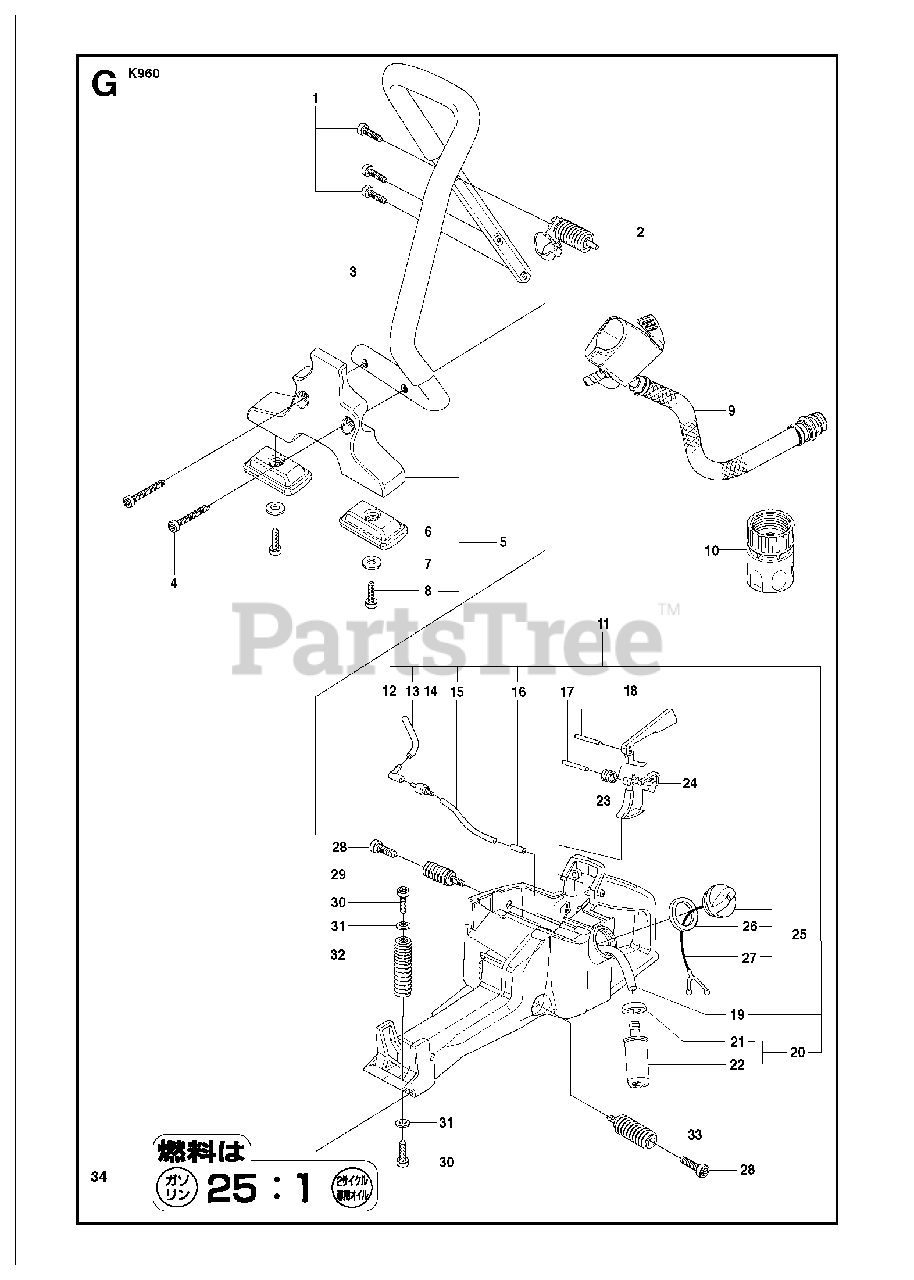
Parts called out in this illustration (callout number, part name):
1	SCREW ITXSCT
2	ANTIVIBRATION ELEMENT
4	SCREW ITXSCT
5	GROUND SUPPORT08-jun
8	SCREW ITXSCM
11	FUEL TANK12-20,
12	CONNECTION BEND
13	FUEL HOSE
15	FUEL HOSE
17	PARALLEL PIN
18	THROTTLE LOCKOUT
19	FUEL HOSE
20	FUEL FILTER21,22
23	SPRING THROTTLE TRIG
25	TANK CAP ASSYIncl. 26, 27
28	SCREW ITXSCM
29	ANTIVIBRATION ELEMENT
30	SCREW ITXSCM
32	ANTIVIBRATION ELEMENT
